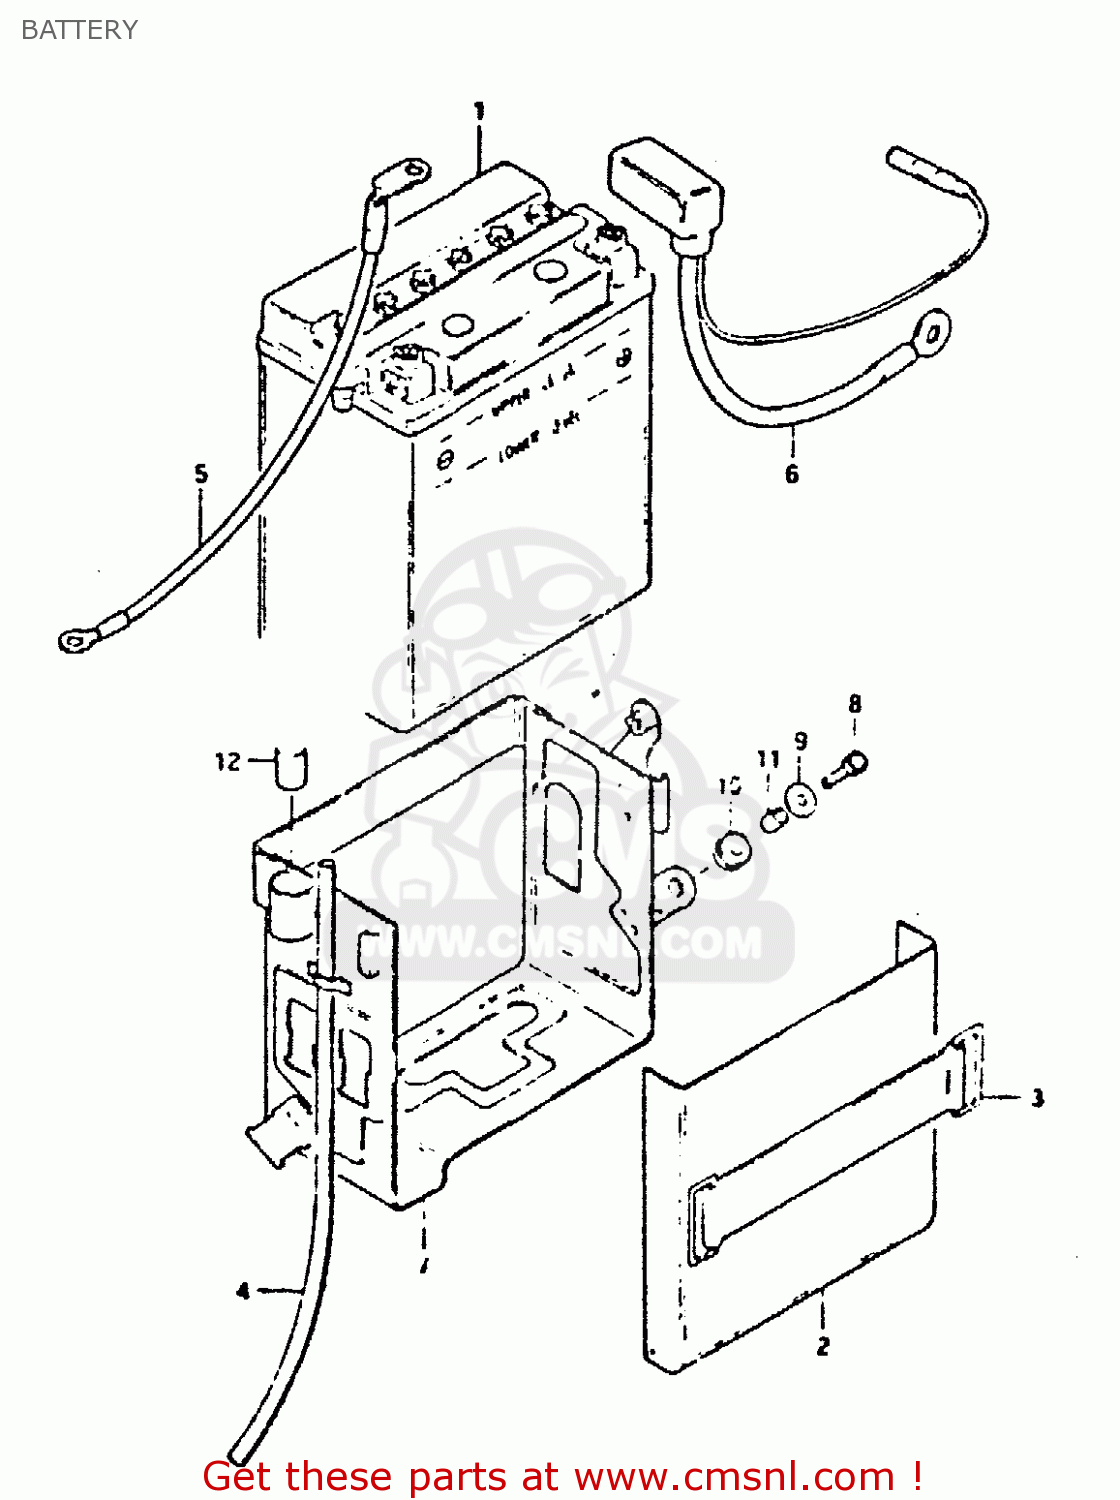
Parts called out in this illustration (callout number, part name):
1	BATTERY ASSY (12V)
2	COVER,BATTERY
3	BAND
4	HOSE,BATTERY EXHAUST
5	CORD,BATTERY MINUS
6	CORD,BATTERY PLUS
7	HOLDER,BATTERY
8	BOLT
9	WASHER
10	CUSHION
11	SPACER(6.1X9X7.5)
12	CUSHION
